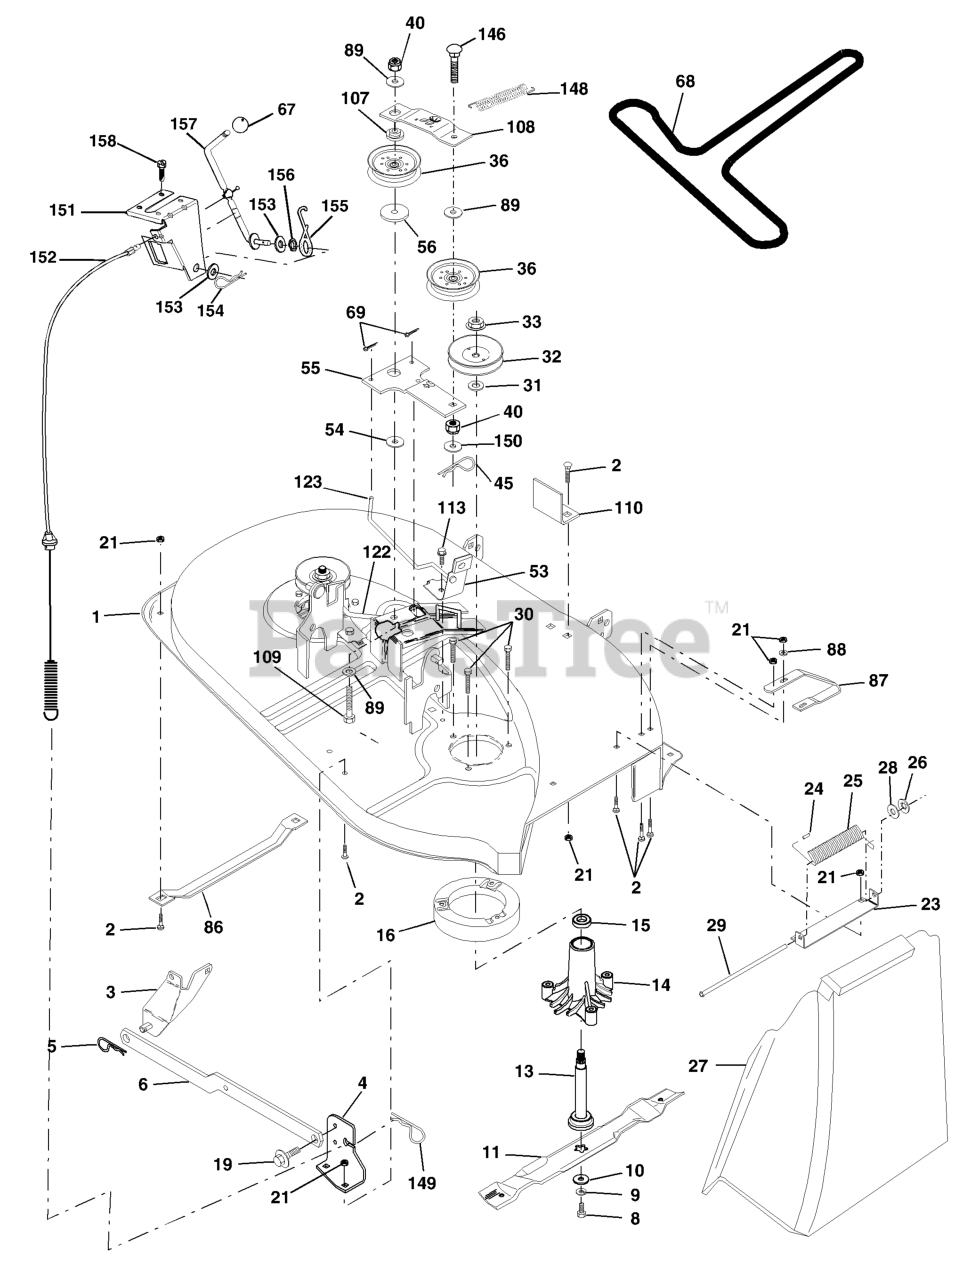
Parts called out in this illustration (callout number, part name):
1	MOWER HOUSING ASM
2	RP BOLT 5/16-18 X3/4 ZN/YEL GR
3	BRKT ASM SWAY BAR
4	BRACKET DECK SWAY BAR 38/42"
5	RETAINER-SPRNG RB
6	REAR SUSP ARM
8	BLADE BOLT
9	LOCKWASHER
10	WASHER.BLADE
11	BLADE.HI.LIFT.38"
13	SHAFT ASM VENT
14	HOUSING.MANDREL.VENTED (MACHD)
16	STRIPPER
19	BOLT SHD 5/16-18
21	LOCKNUT
23	BRACKET, DEFLECTOR
24	CAP-SLEEVE LT
25	SPRING TORSION
26	NUT PUSH M
27	SHIELD, DEFLECTOR
28	Washer 11/32 x 5/8 x 16 Gauge
29	ROD-HINGE T
30	SCREW THDROL ROLLING WASHER HD
31	WASHER
32	PULLEY MANDREL
33	NUT
36	FLAT IDLER PULLEY
40	Nut, Crownlock 3/8-16 Unc
45	RETAINER M
53	BRAKE ASSEMBLY
54	HARDENED WASHER
55	IDLER ARM
56	SPACER.RETAINER.MOWER
67	KNOB T (3/8 HOLE)
68	V-BELT TRIPATH
69	COTTER PIN
86	RUNNER-LH M
87	RUNNER.RH.38
88	WASHER M
89	WASHER GT
107	SPACER.IDLER.ARM
108	STIFFENER.IDLER.ARM
109	Bolt, Hex Hd 3/8-16 x 2-1/2
110	UPSTOP DECK FRONT 38"
113	SCREW 5/16"
122	BRAKE ROD LH
123	ROD.BRAKE.MANDREL.RH
146	BOLT, CARRIAGE IDLER
148	IDLER RETURN SPRING
149	SPRING.RETAINER.YELLOW.ZINC
150	WASHER PM
151	BRACKET.CLUTCH.CABLE
152	CLUTCH CABLE 38"/46"
153	WASHER FLAT 3/8"
154	SPRING RETAINER
155	SPRING RETENTION LEVER
156	SPACER.CLUTCH.CABLE
157	ROD CLUTCH CABLE 3/8"
158	SCREW LT
